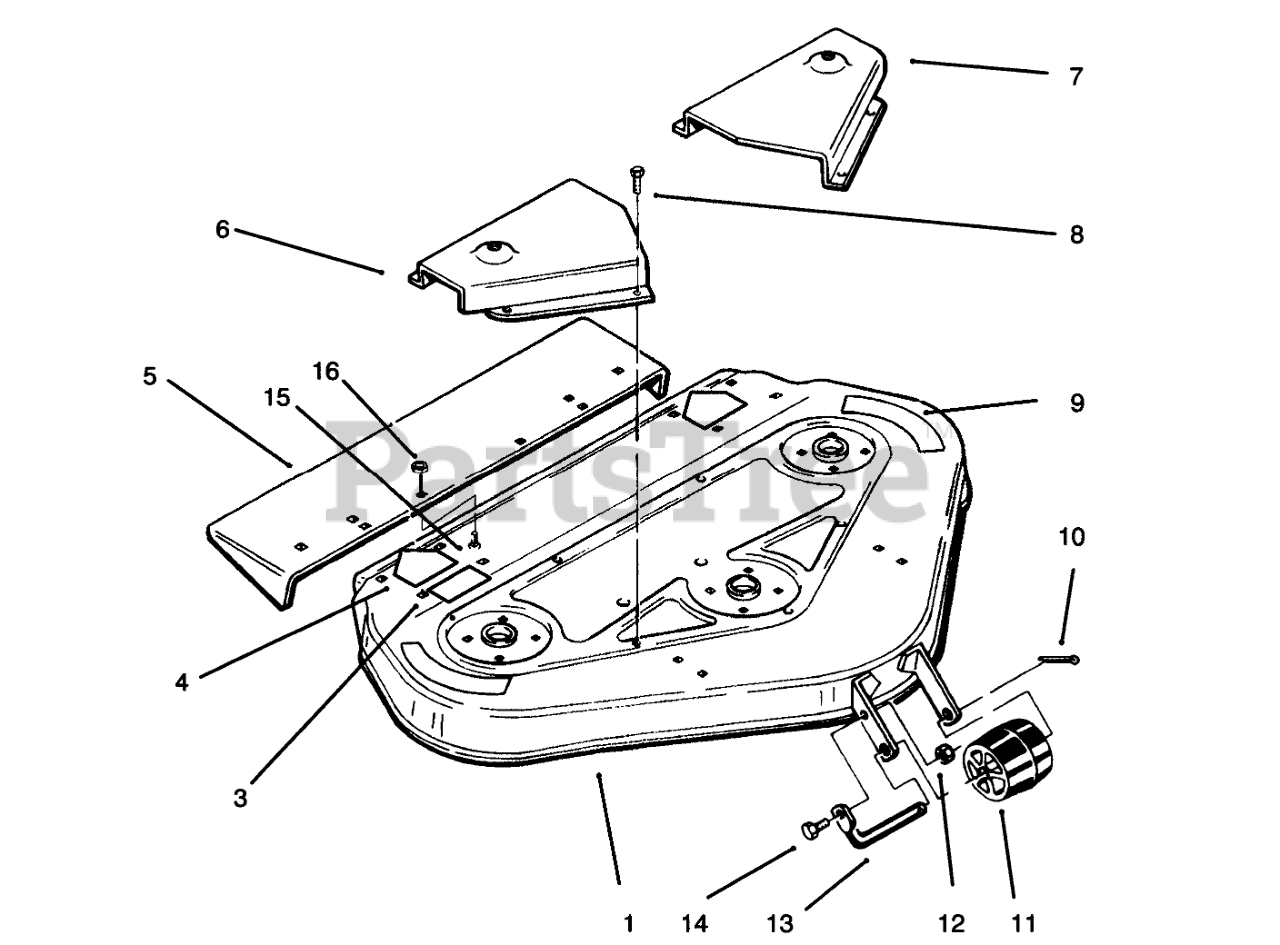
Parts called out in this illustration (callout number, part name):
1	Deck Ass-y (Incl. Ref. #4 & 9)
3	DECAL-HEIGHT & BELT
4	DECAL-DANGER
5	Chute Extension
6	Belt Cover RH
7	Cover-Belt
8	SCREW-HWH
9	DECAL-DANGER
10	PIN-COTTER
11	Roller
12	NUT-LOCK, NI
13	ROLLER-SHAFT
14	SCREW-HH
15	BOLT-CARR
16	NUT-LOCK, NI
